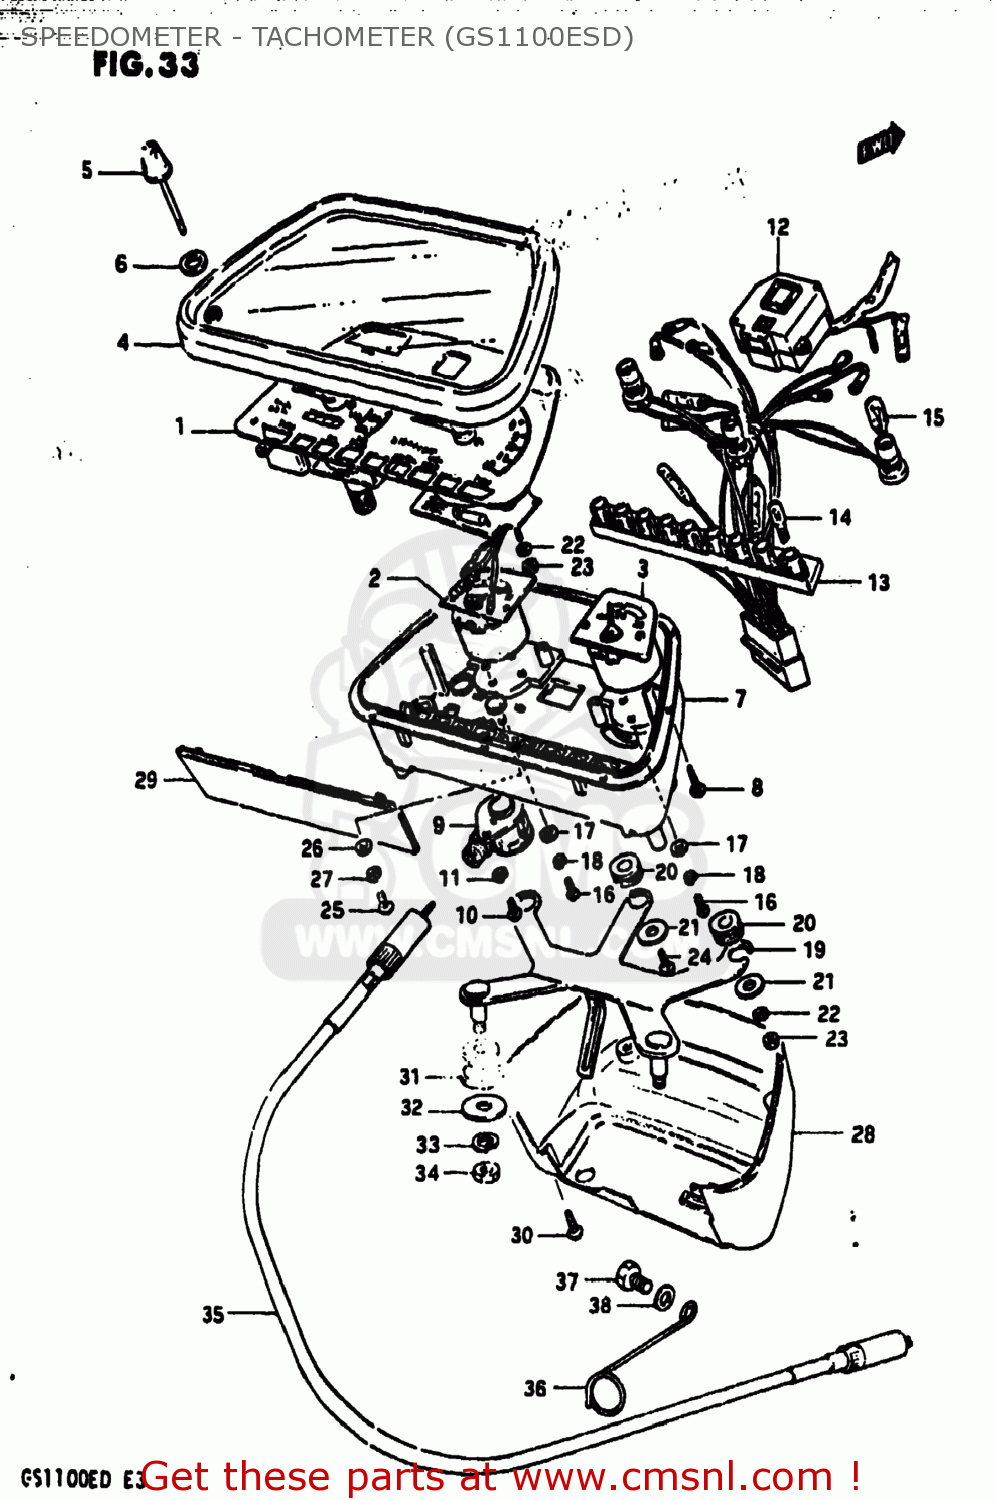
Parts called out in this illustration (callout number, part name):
1	METER,SPEEDOMETER/TACHOMETER (KM/
2	METER,FUEL
3	METER,OIL TEMPERATURE
4	HOOD,METER
5	KNOB,TRIP METER
6	SEAL,TRIP KNOB
7	CASE,METER,INNER
8	SCREW
9	GEAR BOX,SPEEDOMETER
10	SCREW 4X10
11	LOCK WASHER
12	INDICATOR ASSEMBLY,GEAR POSITION
13	SOCKET UNIT,METER
14	BULB(12V3W,WB371,T7)
15	BULB(12V3.4W,T10,BF175-01450A)
16	SCREW 3X12
17	WASHER
18	LOCK WASHER
19	BRACKET,METER
20	CUSHION
21	WASHER,COMBINATION METER
22	WASHER
23	NUT 4MM
24	SCREW
25	SCREW
26	WASHER
27	LOCK WASHER
28	COVER,METER LWR
29	PLATE,COVER
30	SCREW
31	CUSHION,METER BRACKET
32	WASHER (8.5X20X1.6)
33	LOCK WASHER
34	NUT
35	CABLE ASSEMBLY,SPEEDOMETER
36	CLAMP,SPEEDOMETER CABLE
37	BOLT, UPPER
38	WASHER
